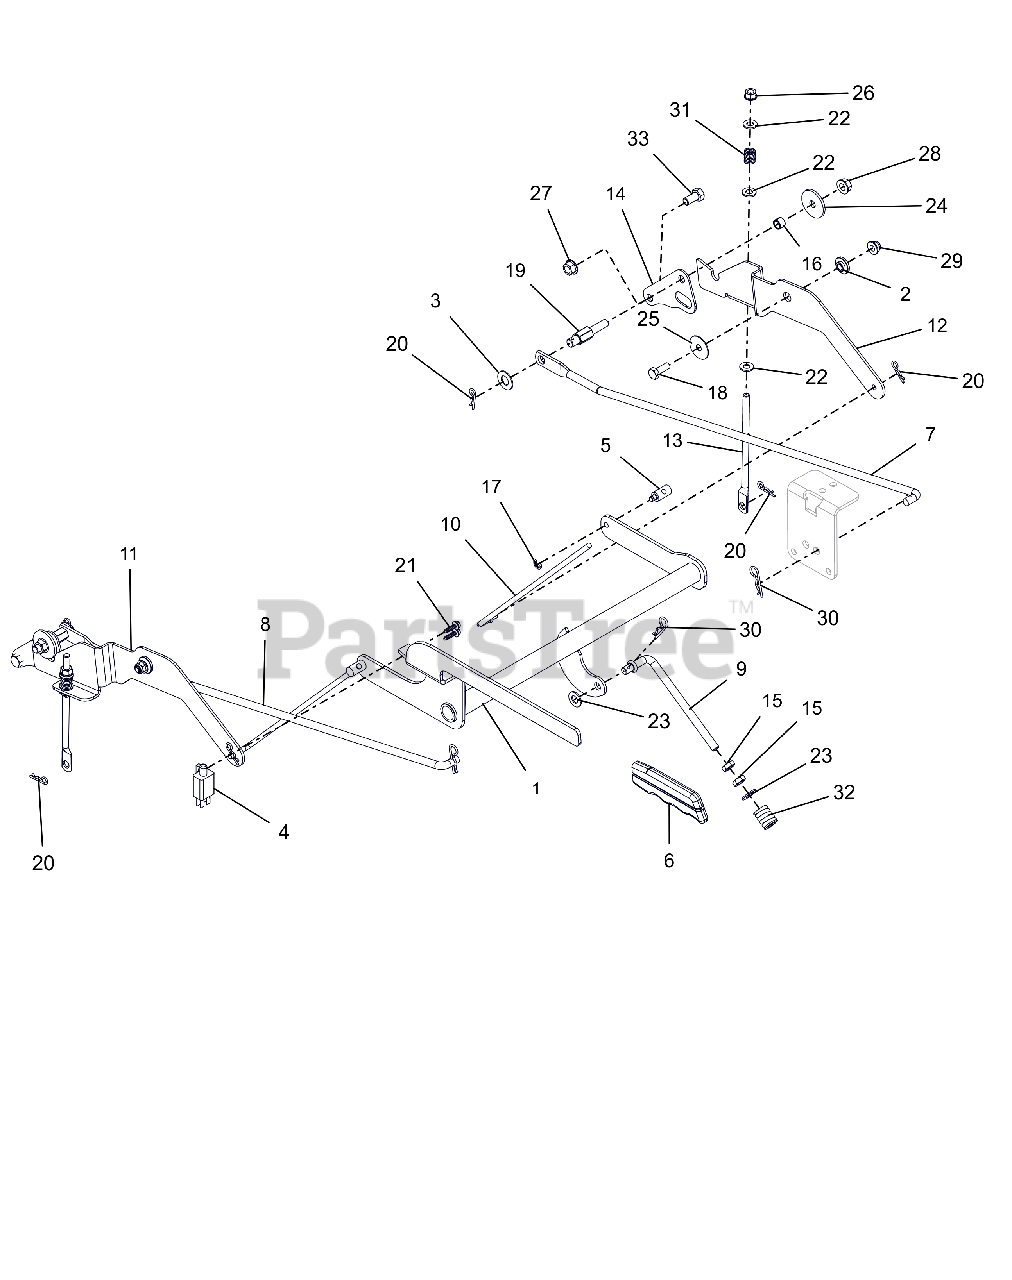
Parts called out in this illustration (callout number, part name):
1	WLDMT, BRAKE LEVER
2	BSHG, FLG .325X.499X.26X.88
3	WSHR, FLT .505X1.00X.062 ZCC
4	SWITCH- DOUBLE POLE N.O./N.O.
5	TRUNION, 1/4-20
6	GRIP, PARKING BRAKE (YELLOW)
7	LINKAGE, STEERING - LH
8	LINKAGE, STEERING - RH
9	LINK, OVER CENTER, PARKING BRK
10	LINK, BRAKE ARM
11	INTERLOCK, RH BRAKE LINK
12	INTERLOCK, LH BRAKE LINK
13	LINK, BRAKE COG
14	PLATE, TRANSAXLE ADAPTOR
15	NUT-JAM .375-16 G2 ZCC
16	SPCR, SLV .385X.500X.350
17	RG-RTNG-EXT .250X.025
18	BLT, HEX .31-18X.875 G5 ZCC
19	POST, STEERING LINK MOUNTING
20	PIN, HAIR #213 .08X1.19 ZCC
21	SCR, PLASTITE #12X.75 ZCC
22	WSHR,FLT .344X.688X.065 ZCC
23	WSHR,FLT .406X.812X.065 ZCC
24	WSHR, FLT .380X1.50X.125 ZCC
25	WSHR, FLT .347X1.254X.048 ZCC
26	NUT,LK-CTR-FLG .31-18 GF ZCC
27	NUT-LK-TOP-FLG .38-16 ZC120
28	NUT-LK-CTR-FLG .375-16 GF ZCC
29	NUT,LK-NYL-FLG .31-18 G5ZC120
30	PIN, HAIR #203 .09X1.50 ZCC
31	SPRING, COMPRESSION
32	SG-COMP .187X.56X1.62
33	BLT,HEX .38-16X.75 G5 ZCC
